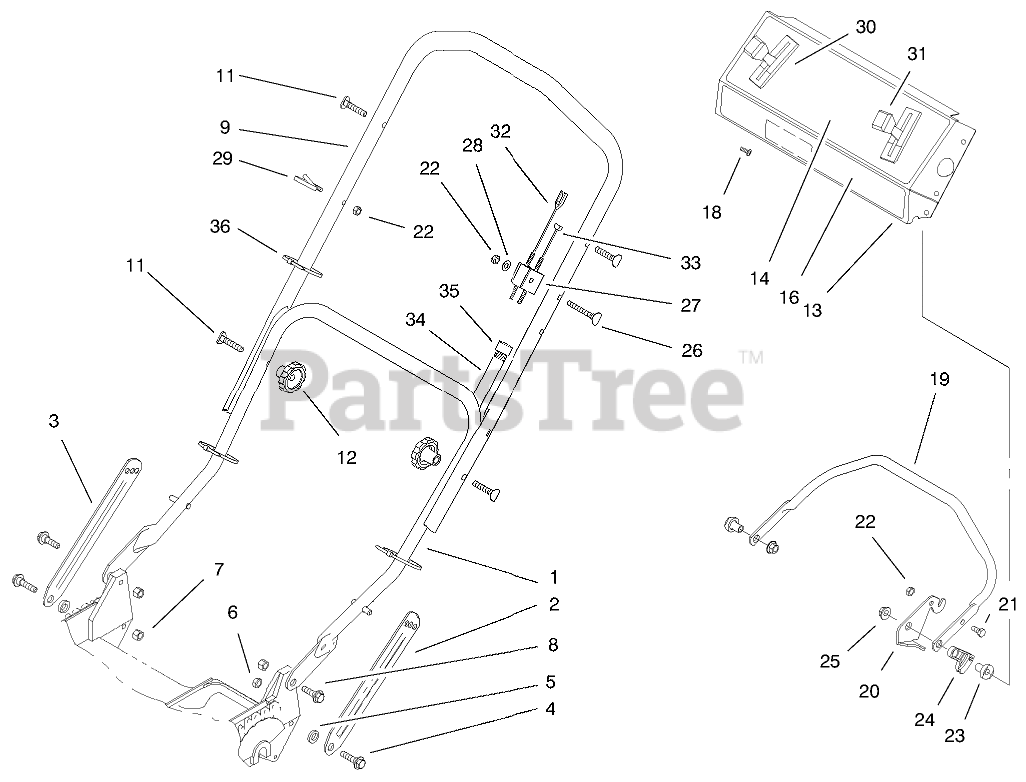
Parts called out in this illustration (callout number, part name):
1	ASM-Handle
2	Latch-Handle
3	Latch-Handle
4	SCREW-SHOULDER
5	SPACER
6	NUT-LOCK, NI
7	NUT-LOCK, NI
8	SCREW-SHOULDER
9	HANDLE - DIPPED
11	SCREW-HANDLE
13	Panel-Control (Incl. Ref. #14)
14	DECAL - INSTRUCTION
16	DECAL - CONSOLE
18	SCREW-TAP
19	Bar-Control
20	Lever-Control
21	SCREW-HH
22	NUT-LOCK, NI
23	SPACER-SUPPORT
24	LEVER-TRACTION
25	NUT-LOCK NI
26	SCREW-HANDLE
27	SUPPORT-CABLE
28	WASHER-FLAT
29	GUIDE-ROPE
30	CONTROL-SPEED, GROUND
31	THROTTLE CONTROL
32	BRAKE CONTROL
33	CABLE-TRACTION
34	CONTROL CABLE COVER
35	FITTING-RING
36	TIE-CABLE
